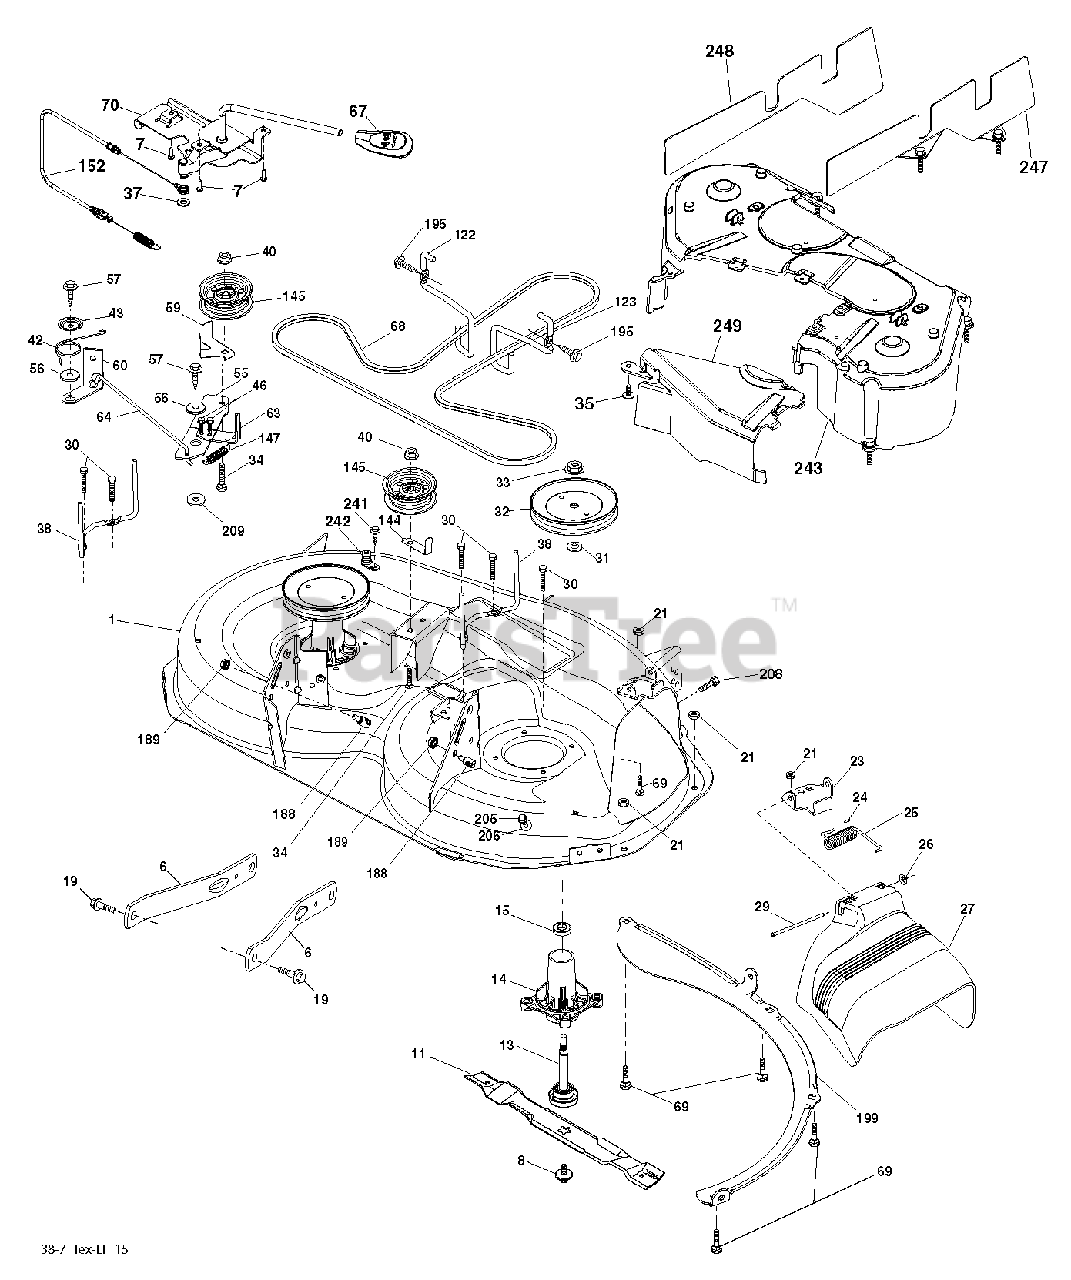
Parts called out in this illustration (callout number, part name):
6	ARM.SUSPENSION.MOWER.R
7	SCREW.#10 X 0.750.BOS THREAD
8	BOLT.WASHER.ASM.7/16-2
11	BLADE 38" PREMIUM
13	SHAFT.ASM.MDRL.N/GREASE.38
14	HOUSING MANDREL
19	BOLT.SHOULDER
21	LOCKNUT
23	BRKT.DEFLECTOR.38"2005+
24	CAP-SLEEVE LT
25	SPRING.TORSION.DEFLECT
26	NUT PUSH M
29	ROD.HINGE
30	SCREW, WASHER HEAD
31	WASHER.SPACER.MANDREL
32	PULLEY.MANDREL.5.0.PD.38"
33	NUT.FLANGE.LOCK.TOP
34	BOLT.3/8-16X1.50
35	FASTENER.XMAS.TREE
38	KEEPER BELT LH MANDREL
40	NUT LOCK FLG 3/8-16 UNC
42	SPRING.TORSION.BRAKE
43	SRPING.TORSION.RETAINE
46	SCREW.1/4-20X5/8
55	IDLER.ARM
56	SPACER.RETAINER
57	SCREW 3/8-16X1
59	GUARD, BELT
60	ARM BRAKE MOWER RH 38"
63	ARM BRAKE MOWER RH
64	LINK BRAKE
67	HANDLE.CLUTCH.CABLE.LT
69	BOLT
70	CLUTCH.ASM.MANUAL.LT.PRED
122	KEEPER BELT ENGINE LH
123	KEEPER BELT RH
144	KEEPER BELT
145	PULLEY.IDLER.48"PRIMARY
147	SPRING RETURN
152	CABLE.CLUTCH.MANUAL.
188	STUD.FASTNER.W/ANTI-ROTATE
189	NUT LOCK HEX FLANGE 5/16-18
195	SCREW, 3/8-16X3/4
199	BAFFLE VORTEX
205	SCREW
208	SCREW 3/8-16X1/2
209	WASHER 12/32X2X10GA
242	PORT.WASHOUT
